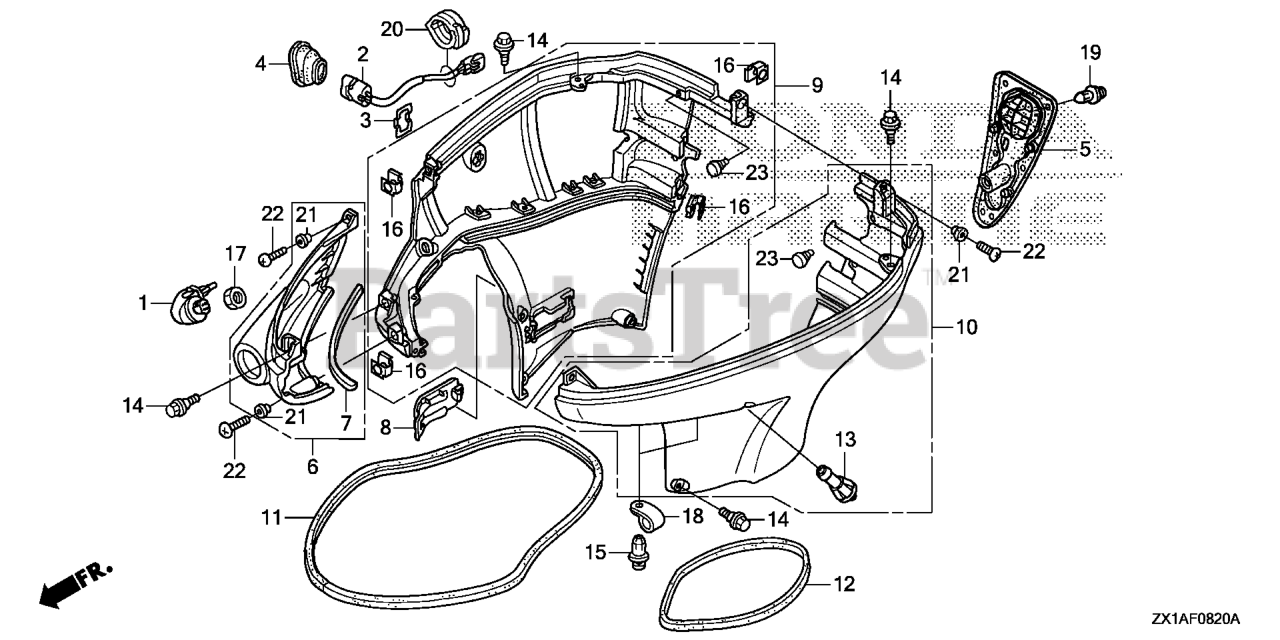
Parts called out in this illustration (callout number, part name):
1	CAP, WATER JOINT
2	SWITCH ASSY., POWER TILT
3	STAY, POWER TILT SWITCH
4	GROMMET, POWER TILT SWITCH
5	GROMMET, COVER (LOWER)
6	COVER, FR. SEPARATE *NHB14M* (AQUA MARINE SILVER METALLIC)
6	COVER,SEPAR*NH565*
7	SEAL, FR. SEPARATE COVER
8	COVER, DRAIN PLUG *NHB14M* (AQUA MARINE SILVER METALLIC)
8	COVER,DRAIN*NH565*
9	COVER, R. ENGINE (LOWER) *NHB14M* (AQUA MARINE SILVER METALLIC)
9	COVER COMP*NH565*
10	COVER, L. ENGINE (LOWER) *NHB14M* (AQUA MARINE SILVER METALLIC)
10	COVER COMP*NH565*
11	SEAL A, COVER (LOWER)
12	SEAL B, COVER (LOWER)
13	GROMMET, WATER CHECK
14	BOLT, SPECIAL (6X17)
15	SCREW, RIVET (5X10)
17	NUT, HEX. (16MM) DUAL QTY = (2) (SINGLE)
18	CLIP (10.7MM)
19	CLIP, SPLASH GUARD
20	CLIP, WIRE HARNESS
21	COLLAR, DISTANCE (6.5X9X11.5)
22	SCREW, PAN (6X25)
23	RUBBER B, STAND STOPPER
